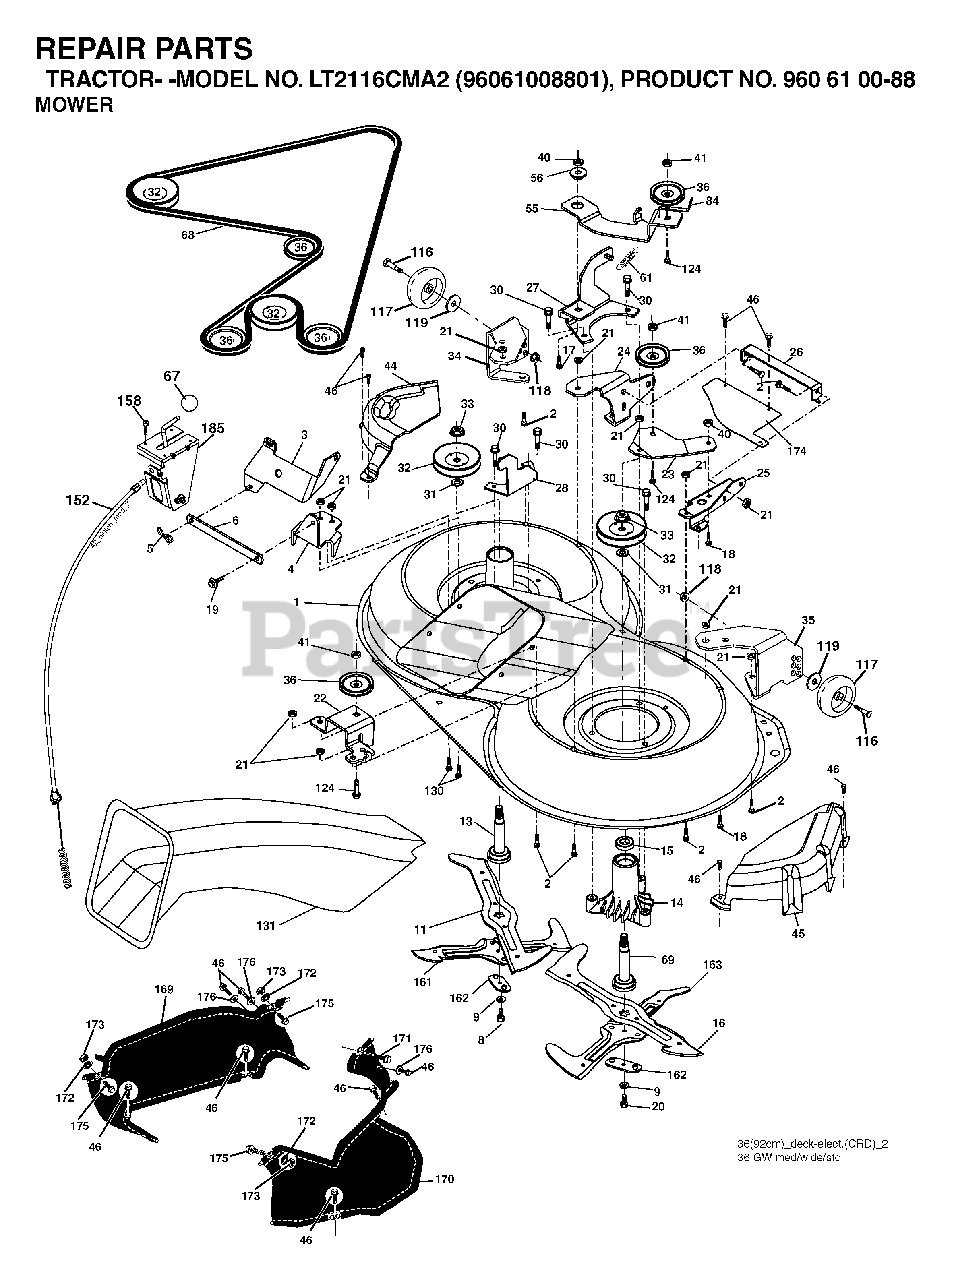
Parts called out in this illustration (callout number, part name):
2	BOLT
3	BRACKET
5	RETAINER-SPRNG RB
6	BAR SWAY
9	LOCKWASHER
13	SHAFT ASM VENT
14	HSG MANDREL
17	BOLT.3/8-14X1.25
19	BOLT SHD 5/16-18
21	LOCKNUT
24	BRACKET
25	BRACKET
28	BRACKET
30	SCREW, WASHER HEAD
31	WASHER.SPACER.MANDREL
32	PULLEY, MANDREL
33	NUT.FLANGE.LOCK.TOP
36	PULLEY.IDLER.4.25
40	LOCKNUT
41	NUT LOCK FLG 3/8-16 UNC
45	MANDREL COVER
46	SCREW.1/4-20X5/8
56	SPACER.RETAINER.MOWER
61	SPRING.TENSION.BELT
67	KNOB T (3/8 HOLE)
68	HEX-BELT
69	SHAFT.ASM.W/LWR.BRG.RH.THREAD
84	KEEPER, BELT IDLER
116	SHOULDER BOLT
117	WHEEL. GUAGE RALLY
118	LOCKNUT
119	WASHER
124	BOLT.3/8-16X1.50
131	CHUTE BAGGER
158	SCREW
169	COVER TERMINAL BATTERY
172	PUSH.NUT.ROUND.3/8.DIAM
173	NUT
185	HEAD ASM. CABLE CLUTCH
